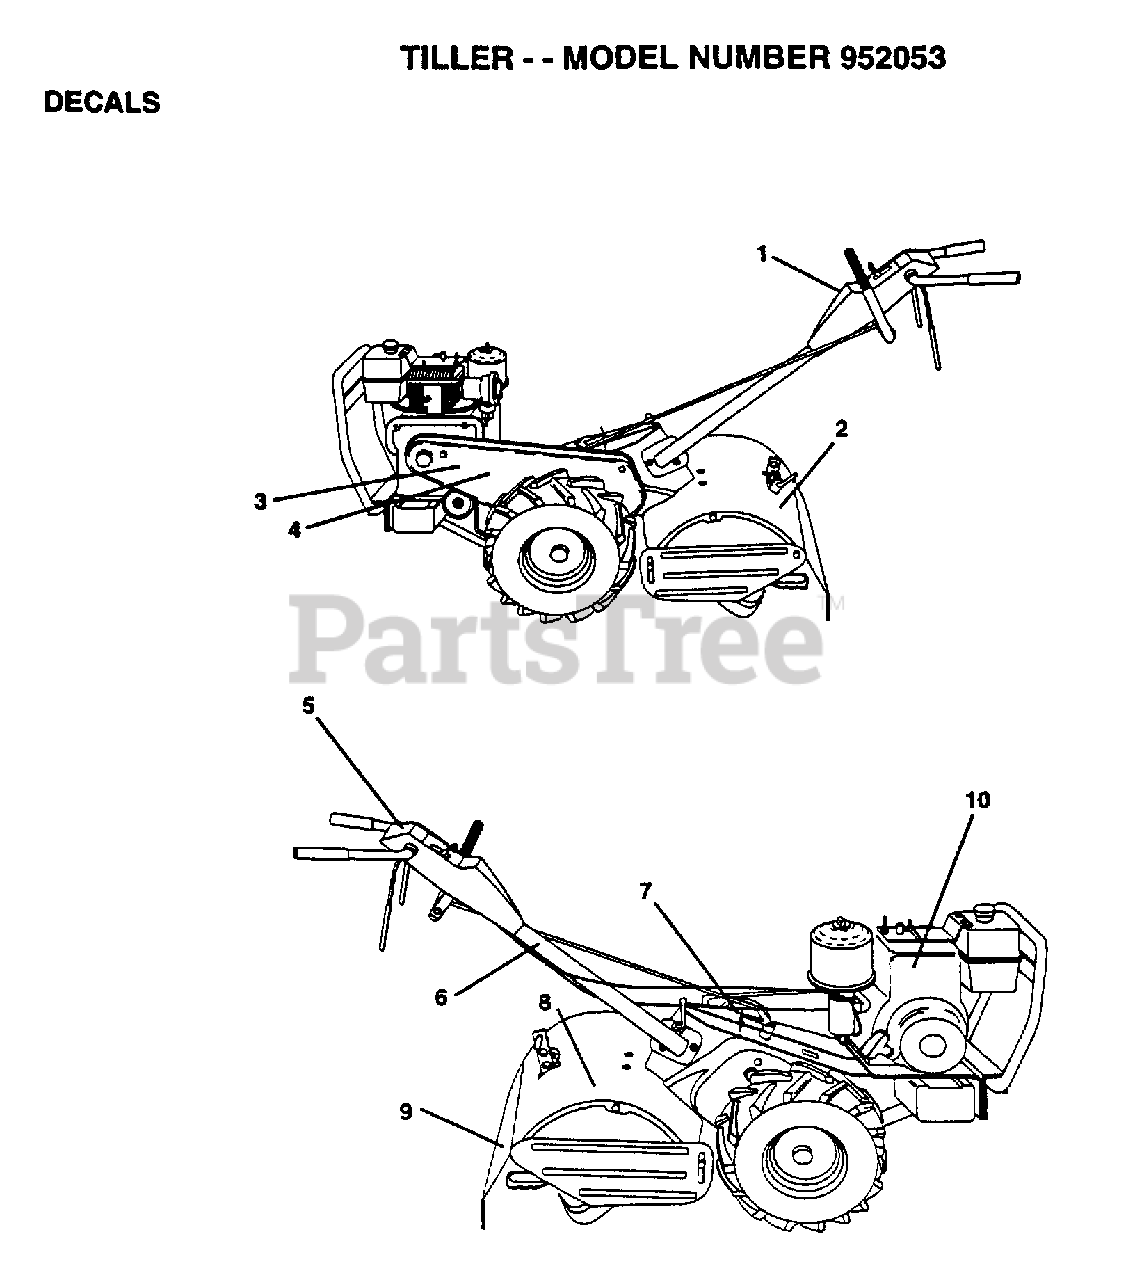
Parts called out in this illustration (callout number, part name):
1	DECAL.PNL.CONTROL
2	DECAL SHIELD TINE
3	DECAL LOGO GUARD
4	DECAL LOGO GUARD
5	DECAL.INST.PNL.CT
6	DECAL TI
7	DECAL.SHIFT.IND.
9	DECAL TI
10	DECAL, BRIGGS & STRATTON
